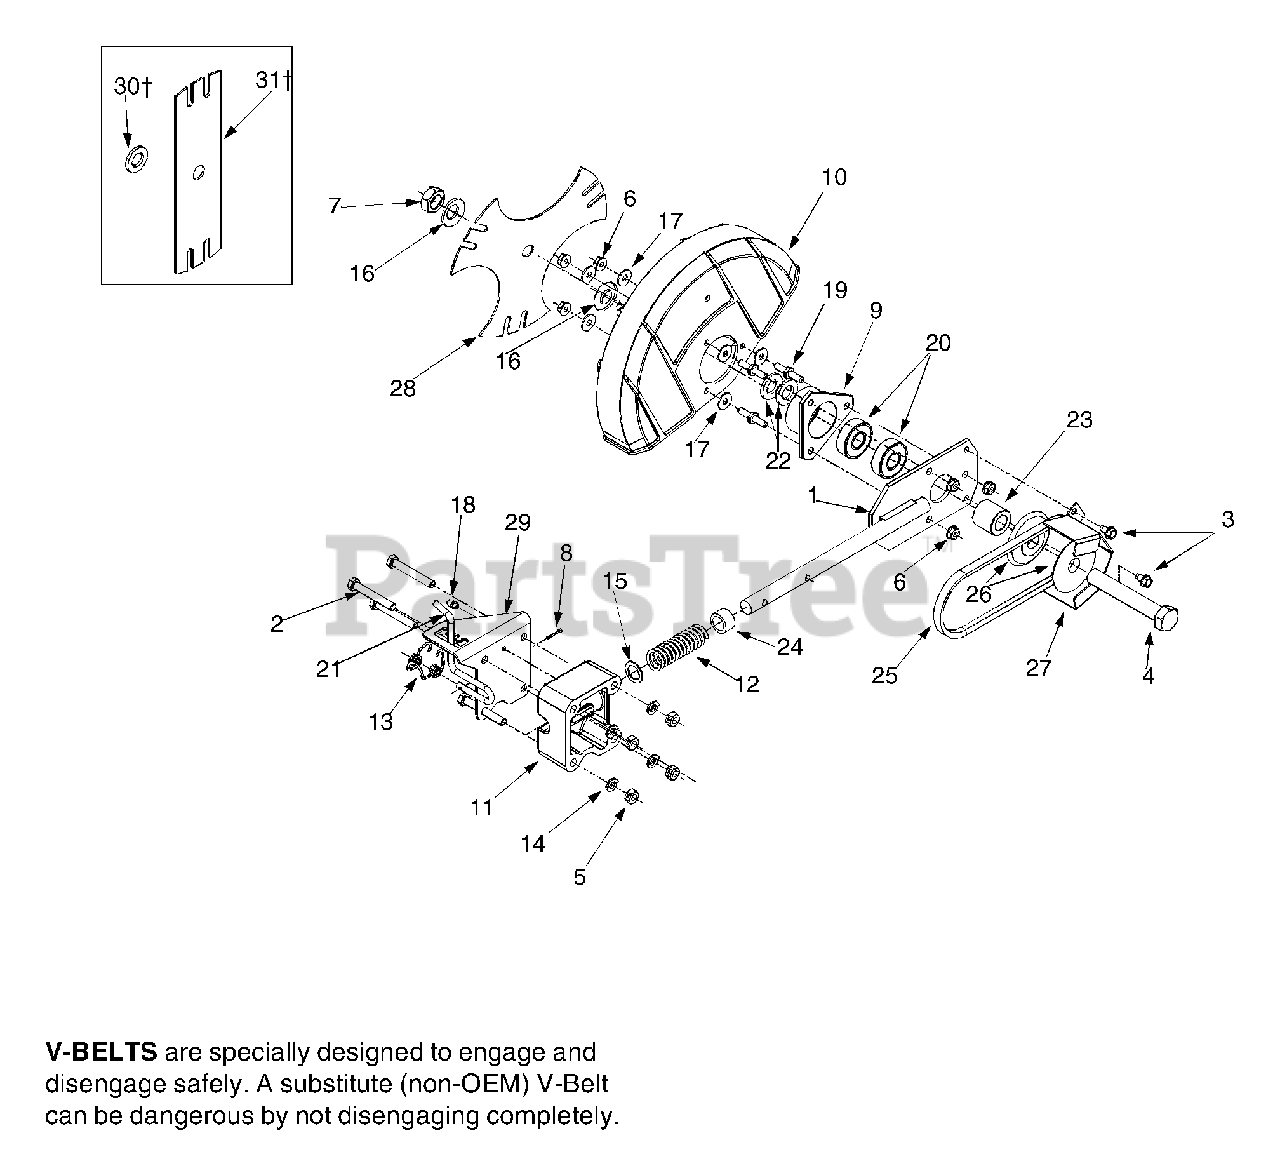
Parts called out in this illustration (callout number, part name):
1	Blade Plate Assembly
2	Hex Screw, 5/16-18
3	Self-tapping Screw, 1/4-20
4	Hex Screw, 5/8-18
5	Hex Lock Nut, 5/16-18
6	Hex Flange Nut, 1/4-20
7	Jam Nut, 5/8-18
8	Cotter Pin
9	Bearing Cup
10	Blade Guard
11	Bearing Block
12	Compression Spring
13	Double Torsion Spring
14	Lock Washer
15	Flat Washer,.632 ID,.943 OD
16	Bell Washer,.63 ID x 1.2 OD
17	Flat Washer,.260 x.72
18	Lube Fitting, 3/16
19	Pin, 1/4-20
20	Bearing,.625 ID x 1.57 OD
21	Blade Adjustment Rod
22	Flat Washer
23	Spacer,.63 x 1.12 x 1.06
24	Spacer,.632 ID x.875 OD
25	Belt
26	Sheave
30	Flat Washer
